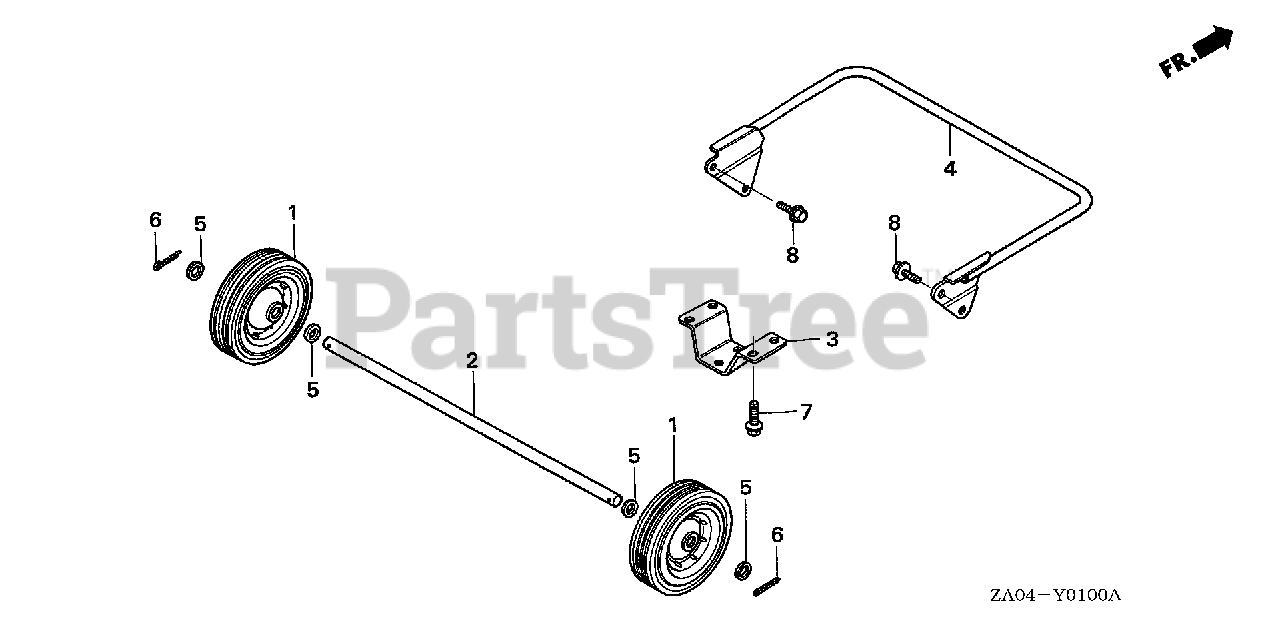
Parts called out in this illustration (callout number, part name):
1	WHEEL (GLEASON 10"X2.75"=254X70)
2	SHAFT, WHEEL
3	STAND
4	PIPE, HANDLE
5	WASHER, PLAIN (20MM)
6	PIN, SPLIT (4.0X28)
6	PIN, COTTER (4.0X30)
7	BOLT, FLANGE (6X12) Use up to Engine SN 1543277.
8	BOLT, FLANGE (8X16) Use up to Frame SN 1008045.
8	BOLT, FLANGE (8X16) Use from Engine SN 1000016.
